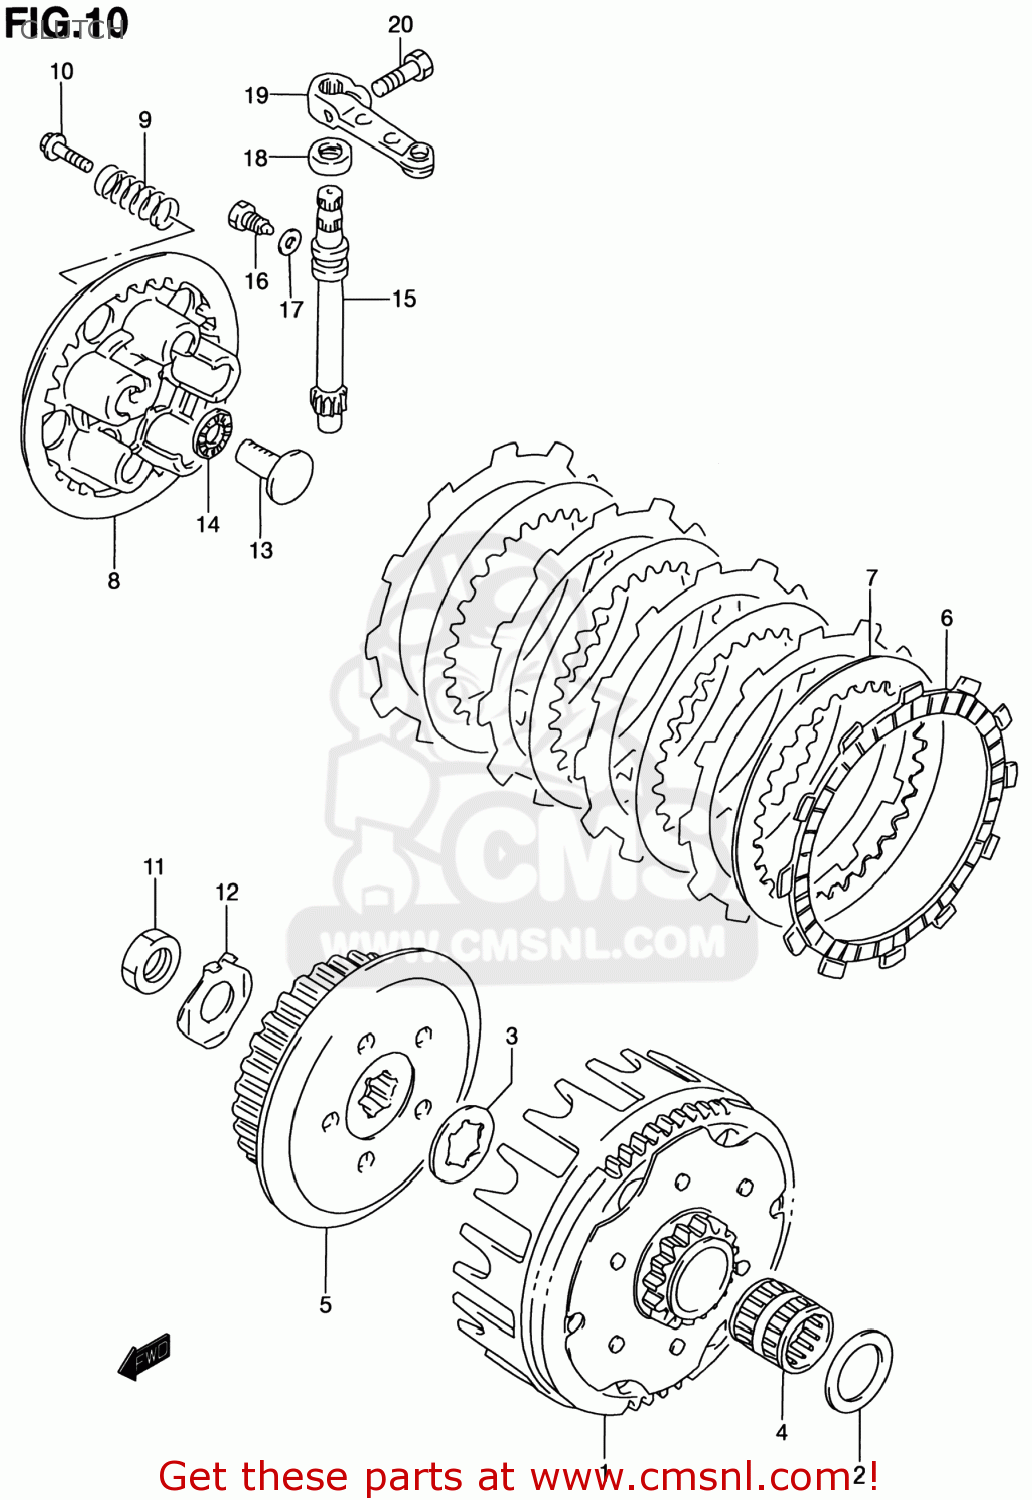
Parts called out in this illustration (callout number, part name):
1	GEAR ASSY,PRI DRIVEN(NT:62/16)
2	SHIM(20X32X1)
3	WASHER,LOCK
4	BEARING(20X25X26)
5	HUB COMP,CLUTCH SLEEVE
6	PLATE,CLUTCH DRIVE(T:3.0) (NAS)
7	PLATE,CLUTCH DRIVEN(T:2.0) (NAS)
8	DISC,CLUTCH PRESSURE
9	SPRING
10	BOLT(5X16)
11	NUT
12	WASHER
13	RACK,CLUTCH RELEASE
14	BEARING(10X22X2.8)
15	PINION,CLUTCH RELEASE
16	BOLT
17	GASKET(6.2X11X1).2 (NAS)
18	SEAL,OIL(10X17X5)
19	ARM,CLUTCH RELEASE
20	BOLT
